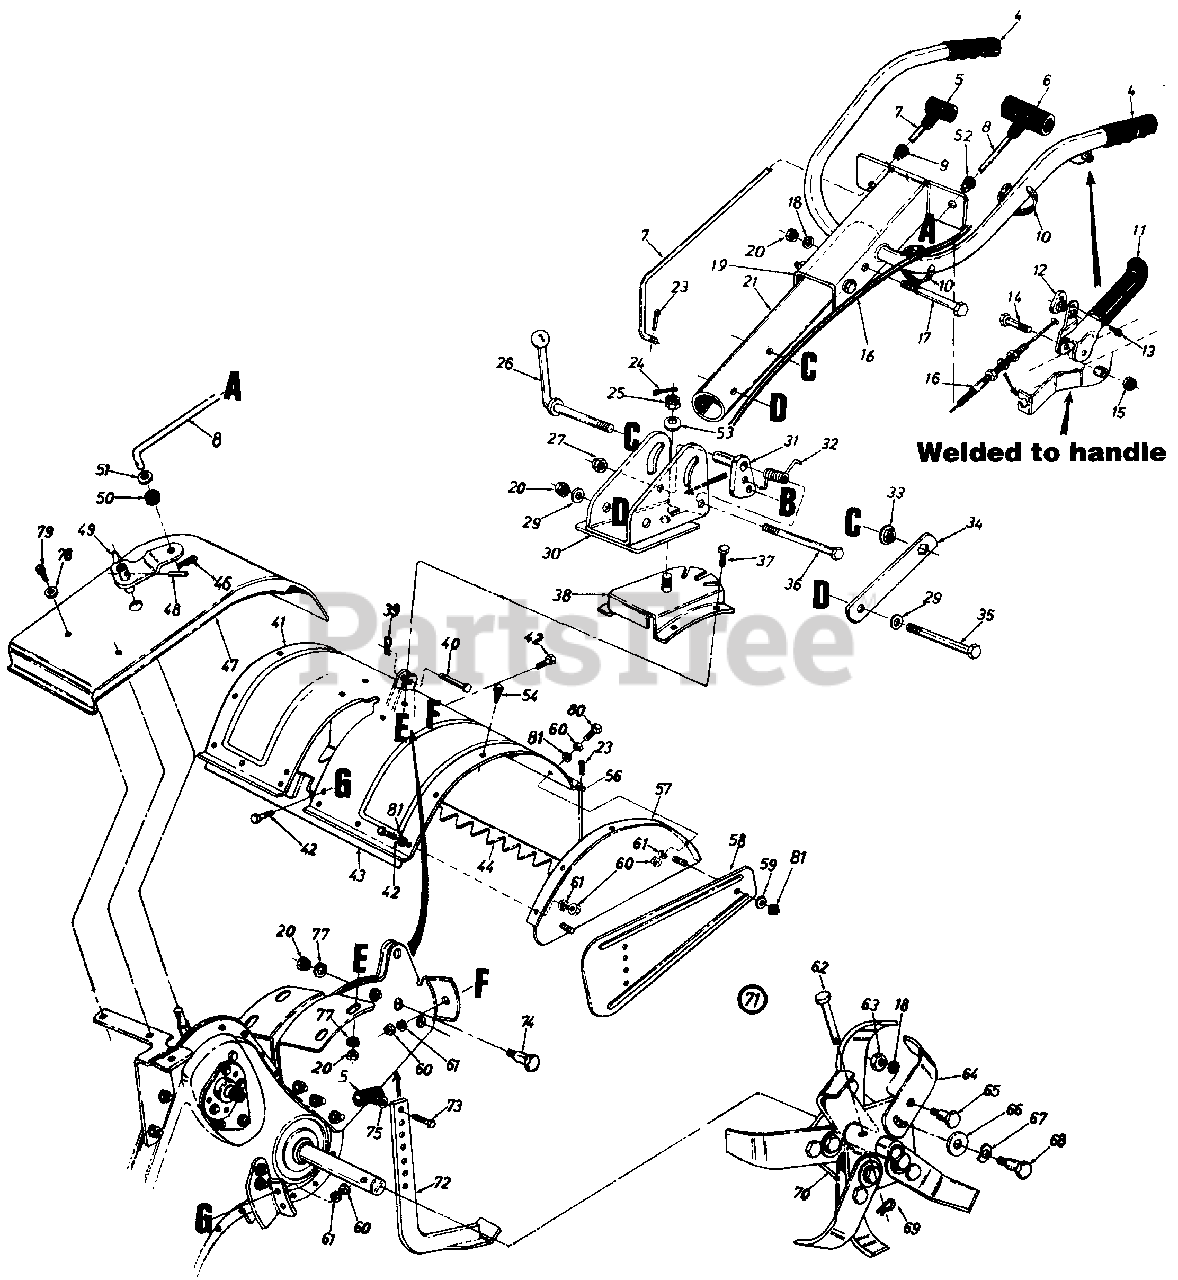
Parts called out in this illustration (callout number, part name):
4	Handle Grip
5	Small "T" Knob
6	Large "T" Knob
7	Clutch Rod
8	Control Rod 37" Lg.
9	Snap On Bushing 3/8" Dia.
10	Cable Tie-Self Clinching
12	Barrel Cable Hold Down
13	Hex B-Tap Scr. #10 x .44" Lg.
14	Hex Bolt 3/8-24 x 2.25" Lg.
15	Hex Jam L-Nut 3/8-24 Thd.
16	Clutch Control Cable 46" Lg.
17	Hex Bolt 3/8-16 x 3.00" Lg.
18	L-Wash. 3/8" I.D. - H.D.
24	Cotter Pin 3/32" Dia. x 1.25" Lg.
25	Hex Slotted Nut 5/8-18 Thd.
26	Handle Adj. Crank
27	Hex Cent. L-Nut 3/8-16 Thd.
29	Bell-Wash. .4" I.D. x .87" O.D.
32	Spring Handle Adj. (Torsion)
33	Hex Flange Nut 3/8-24 Thd.
34	Bracket Hex Nut Retainer
35	Hex Bolt 3/8-16 x 3.25" Lg.
36	Hex Bolt 3/8-16 x 3.00" Lg. - Gr. 8
37	Hex Bolt 3/8-16 x 1" Lg.
40	Clevis Pin .375" Dia.
43	Bracket Reinforcement - 18"
46	Intern. Cotter Pin 5/16" Dia.
49	Shifting Crank Ass'y.
50	Rubber Washer .33" I.D.
51	Fl-Wash. .4" I.D. x 1.25" O.D.
52	Snap On Bushing 1/2" Dia.
53	Bell-Wash. .63" I.D. x 1.25"
54	Hex Wash. Tap Scr.
56	Tiller Flap Rod
60	Hex Nut 5/16-18 Thd.
61	L-Wash. 5/16" I.D.
62	Clevis Pin .375" Dia.
63	Hex Nut 3/8-24 Thd.
65	Shld. Bolt 1/2" Dia. x .175
66	Fl-Wash. .51" I.D. x 1.50"
67	Bell-Wash. .515" I.D. x 1.14"
68	Shld. Bolt 1/2" Dia. x .320
69	Intern. Cotter Pin
73	Hex Bolt 3/8-16 x .75" Lg.
74	Shld. Bolt 1/2" I.D. x .62" Lg.
75	Fl-Wash. 3/8" I.D. x 5/8" O.D.
77	L-Wash. 3/8" I.D.
78	Fl-Wash. .281" I.D. x .62"
79	Hex Wash. Self-Tap Scr. 1/4-20 x .50" Lg.
80	Hex Bolt 5/16-18 x 1-1/4" Lg.
81	Cap L-Nut 5/16-18 Thd.
